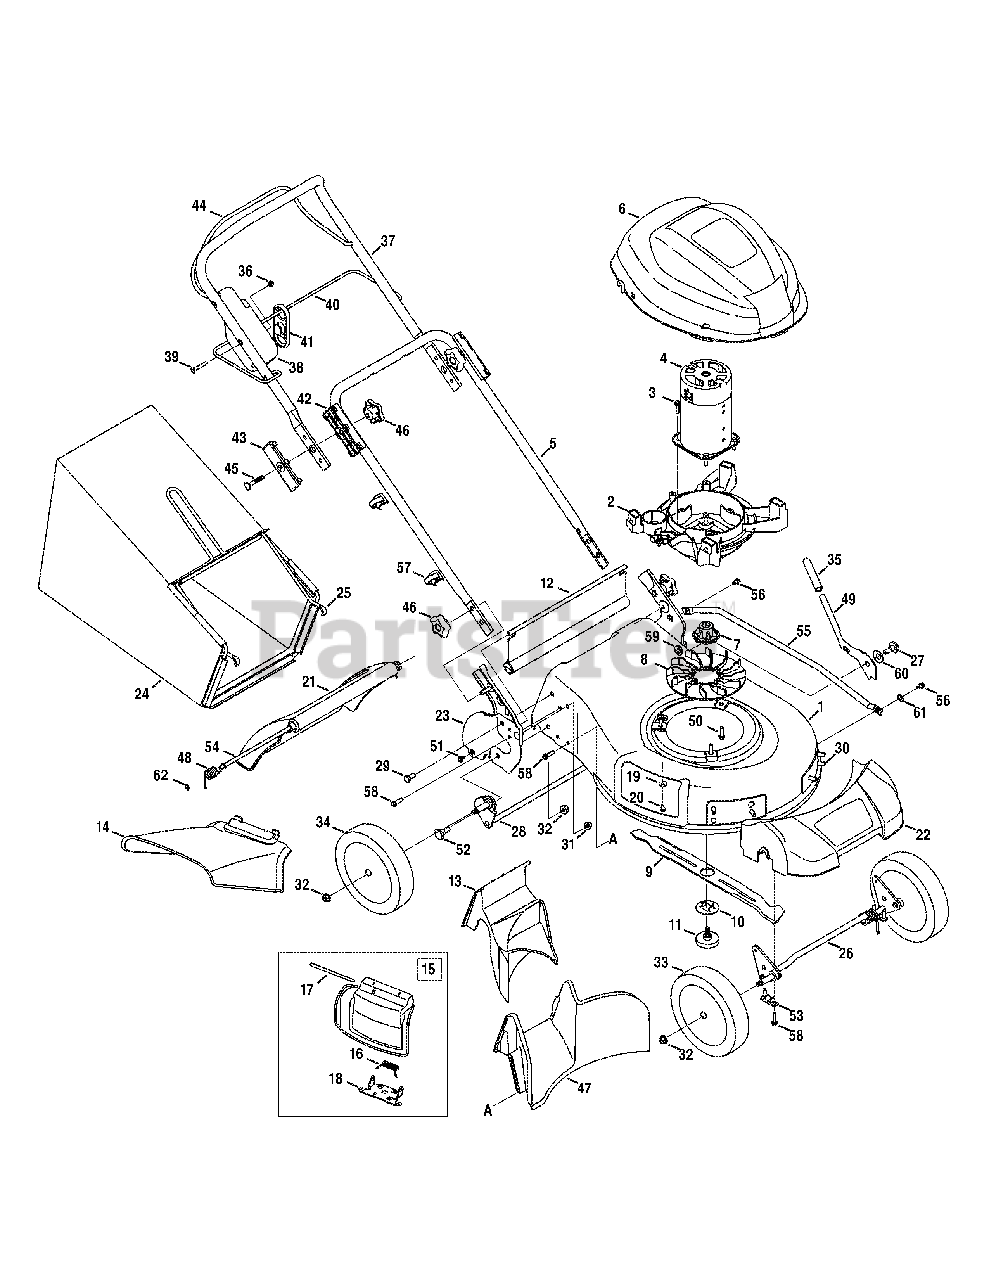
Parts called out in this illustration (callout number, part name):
1	19" Deck
2	Motor Bracket
3	Screw, 1/4-15 x .750
4	Electric Motor, 120V
6	Motor Shroud
7	Blade Hub
8	Electric Fan
9	Mulching Blade
10	Blade Locking Plate
11	Blade Bolt Assembly
12	Trail Shield
13	Rear Mulch Plug
14	Side Discharge Chute
15	Mulch Plug (Incl. 16-18)
16	Torsion Spring
17	Hinge Pin
18	Chute Deflector Adapter
19	Washer, Bell, .265 x .75 x .062
20	Screw
21	Rear Door
22	Front Cover
23	Handle Bracket - RH
23	Handle Bracket - LH
24	Grass Bag
25	Grass Bag Frame
26	Front Bracket Assembly
27	Screw, Shoulder, .50 x .66
28	Rear Bracket Assembly
29	Screw, 5/16-18 x .625
30	Screw, 5/16-14 x .750
31	Nut, Flange Lock, 5/16-18
32	Nut, Flange Lock, 3/8-16
33	Front Wheel
34	Rear Wheel
35	Foam Grip
36	Nut, Hex Lock, 1/4-20
37	Upper Handle
38	Motor/Blade Control
39	Screw, Flat, 1/4-20 x 1.75
40	Guide Rod
41	Cord Retainer
42	Lower Handle Insulator
43	Upper Handle Insulator
44	Motor/Blade Control Handle
45	Bolt Carriage, 5/16-18 x 2.50
46	Star Knob
47	Rear Baffle
48	Door Torsion Spring - RH
48	Door Torsion Spring - LH
49	Spring Lever
50	Screw, 5/16-12 x .750
51	Screw, #10-16 x .500
52	Screw, Shoulder, .500 Dia. x .434
53	Bushing, Lock, .505 Dia. x .62
54	Rear Door Pivot Rod
55	Cross Bracket
56	Screw, Shoulder, 1/4-20 x .50
57	Cable Guide
58	Screw, 1/4-15 x 1.000
59	Spacer, .515 x 1.00 x .310
60	Washer, Bell, .510 x 1.14 x .040
61	Washer, Wave, .390 x .825 x .016
62	Nut, Speed, .3125 ID
